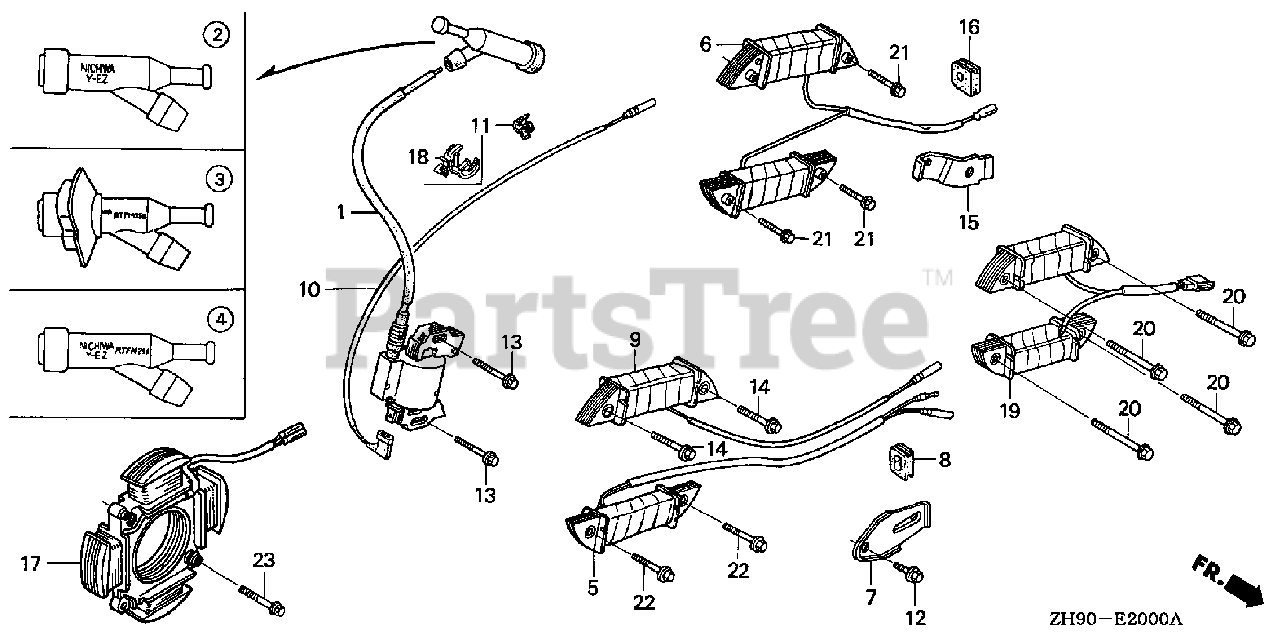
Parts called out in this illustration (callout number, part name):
1	COIL ASSY., IGNITION
4	CAP ASSY., NOISE SUPPRESSOR
8	GROMMET, WIRE
10	WIRE, STOP SWITCH (370MM)
13	BOLT, FLANGE (6X28)
18	CLIP, WIRE HARNESS
